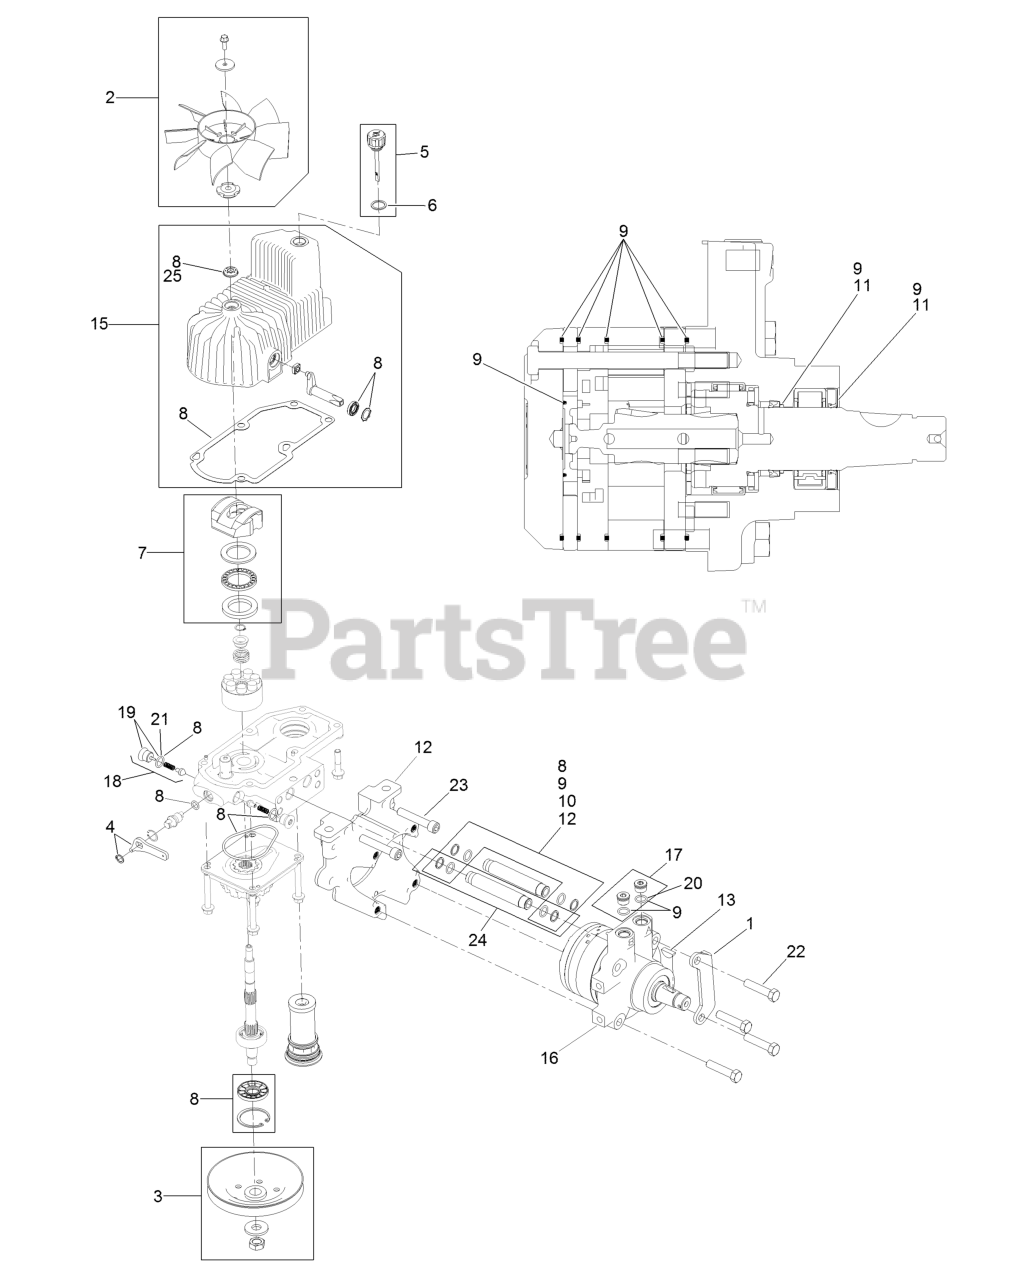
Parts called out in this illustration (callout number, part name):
1	Mount-Shoe, Horse
2	Fan Kit
3	Pulley Kit
4	Handle-Bypass Valve, Hydro
5	Dipstick-Hydro W/Gasket
6	Gasket-Dipstick, Hydro
7	Swash Block Kit
8	Pump Seal Kit
9	Motor Seal Kit
10	Tube Seal Kit
11	Output Shaft Seal Kit
12	Nose Cup-Uht
13	Key-Woodruff
15	Housing-RH
16	Motor-Hydraulic RH 240Cc
17	Magnetic Plugs Service Kit
18	Check Valve ASM
19	Plug-Check (W/O-Ring)
21	O-Ring-Check Valve
22	Screw HH
23	Screw-HSH
24	Hydraulic Tube Kit
25	Seal-Fan Drive
99	Flow Test Kit
99	Puller-Pulley
